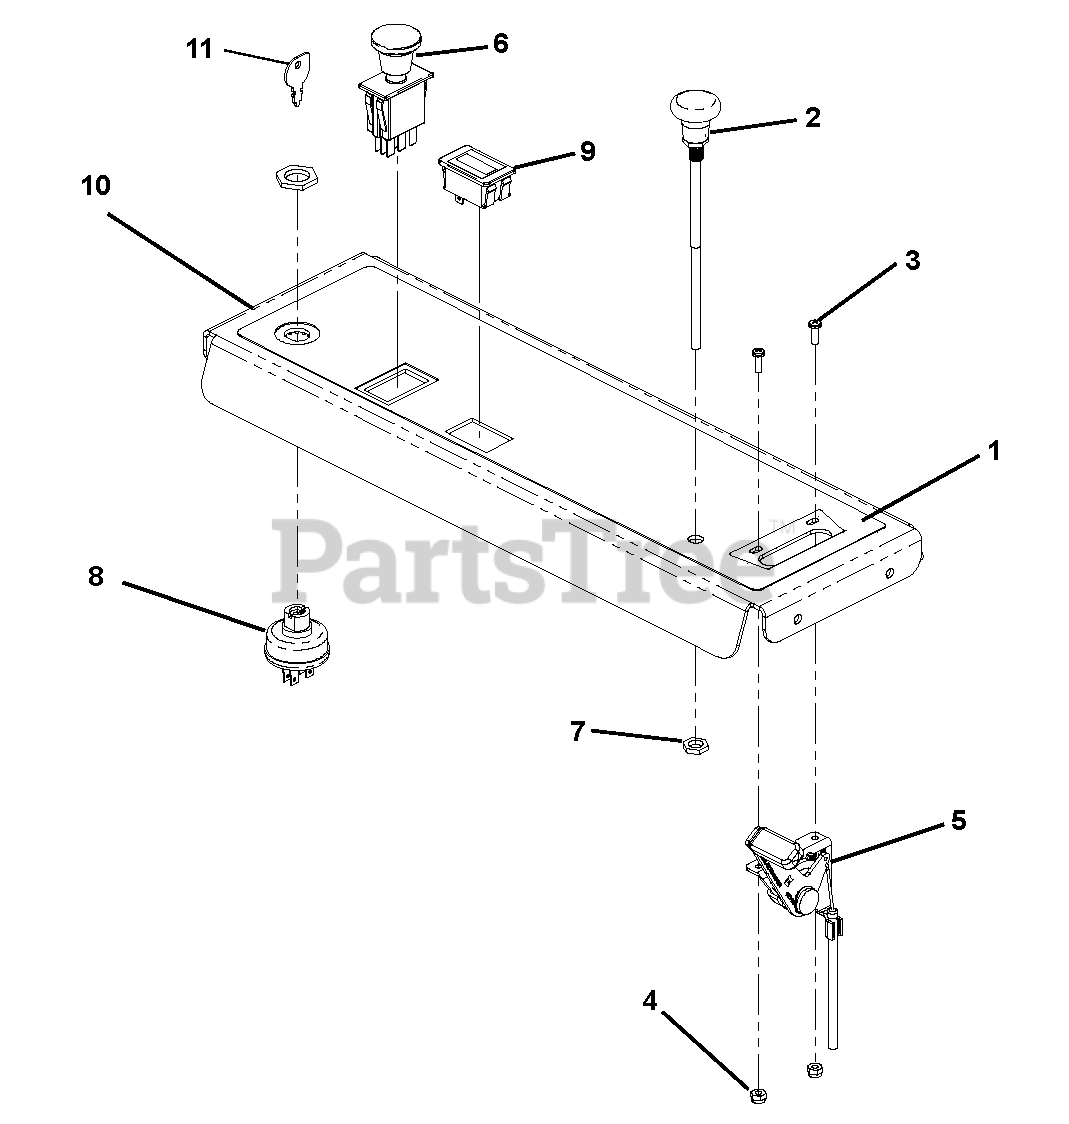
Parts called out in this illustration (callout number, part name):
1	Decal, Console Pro Stance
2	Cable, Choke
3	Screw, 8-32 x .5
4	Nut, Elastic Stop 8-32
5	Cable, Throttle
6	Switch, Clutch (With Graphic) (PTO)
7	Nut, 3/8 UNF Hex Grade 5
8	Switch, Key - 3 Position (Inclludes item 13)
9	Meter, Hour w/Maintenance
10	Assembly, Control Panel w/Decals
11	Key, Ignition (Service Only)
